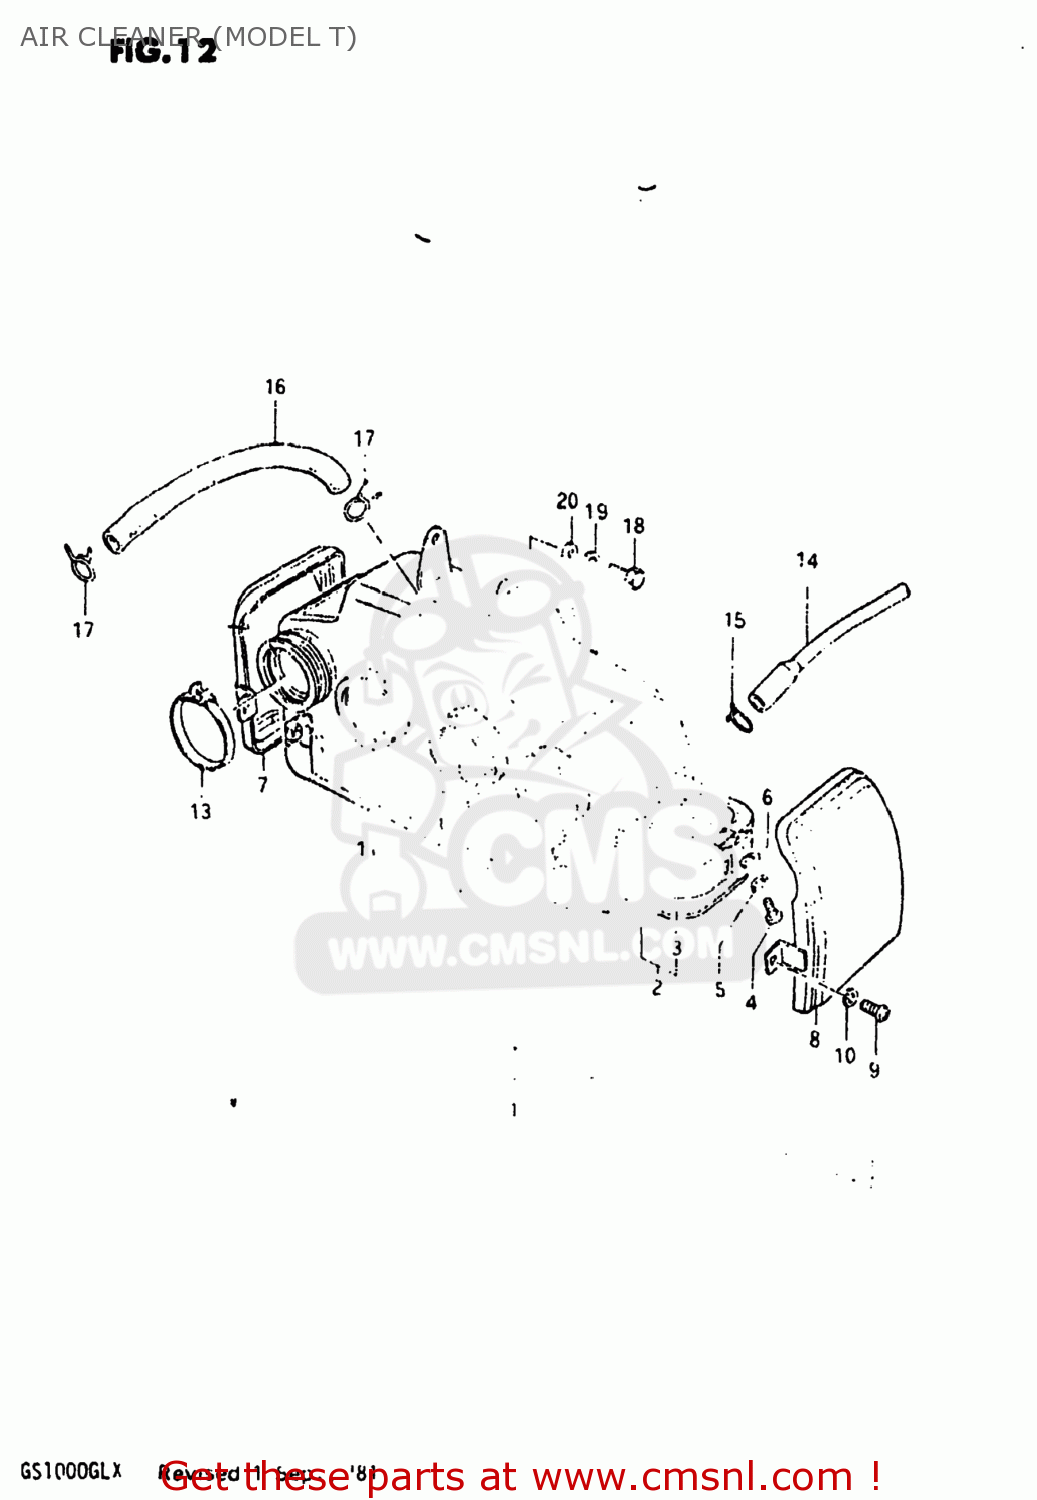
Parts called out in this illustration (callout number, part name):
1	CLEANER ASSEMBLY,AIR
2	FILTER ASSY,AIR CLEANER
3	FILTER
4	SCREW
5	LOCK WASHER
6	WASHER
7	CAP,AIR CLEANER,RIGHT
8	COVER, LH
9	SCREW
10	LOCK WASHER
11	HOSE,R
12	HOSE,L
13	CLAMP
14	15
15	16
16	HOSE
17	CLIP
18	BOLT
19	LOCK WASHER
20	WASHER
